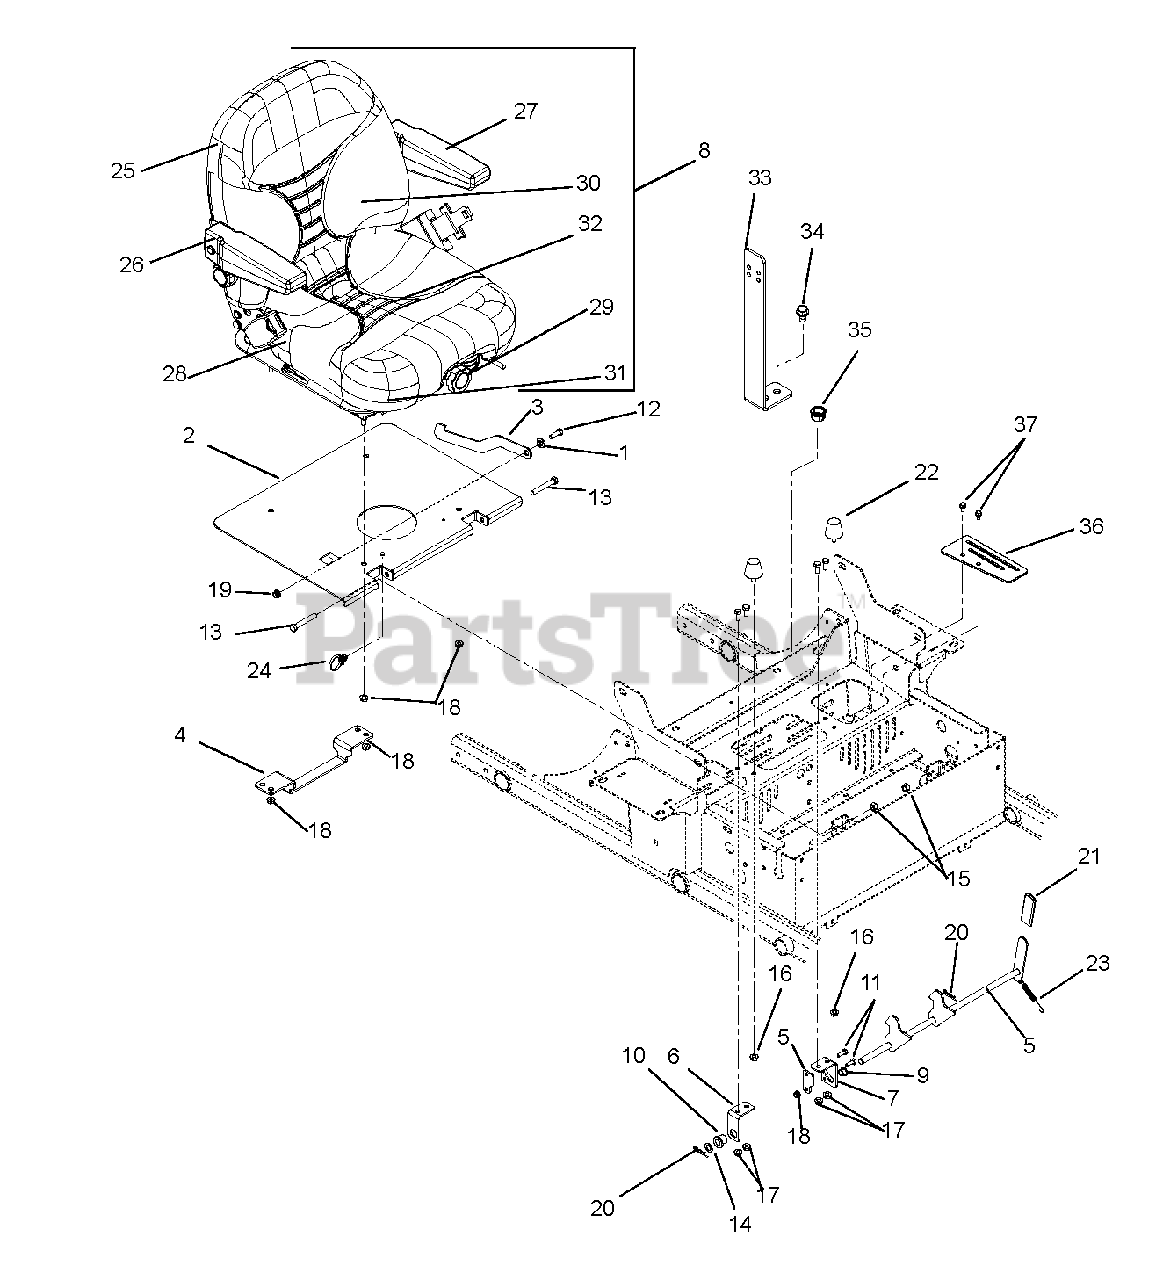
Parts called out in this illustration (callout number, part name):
1	Bushing, Flange .325 x .499 x .26 x .88
2	Seat Plate Weldment - Black
3	Stop, Seat Pivot
4	Bracket, Seat Latch
5	1Weldment, Seat Latch
6	Mount, Seat Latch -RH
7	Mount, Seat Latch -LH
8	Seat, SUSP, w/Seat Belt, LT GRY
9	Bushing, Polyliner - .50 Split
10	Bushing, Flange .515 x .750 x .745 x 1.00NY
11	Bolt, Hex .25-20 x .75 GR5 YWZC
12	Bolt, Hex .31-18 x .75 GR5 YWZC
13	Bolt, Hex .38-16 x 2.50 GR5 YWZC
14	Washer, Flat Steel .52 x .827 x .062 YWZC
15	Nut, Locking Center .38-16 YWZC
16	Nut, Spin Lock-Flange .312-18 YWZC
17	Nut, Locking Top-Flange .31-18 YWZC
18	Nut, Locking Top-Flange .25-20 YWZC
19	Nut, Locking Nylon-Flange .31-18 YWZC
20	Pin, Hair-Internal .08 x .38 x 1.42 YWZC
22	Bumper, Rubber Cone, Stud Mount
23	Spring, Tension .043 x .44 x 3.31 WLD 5.8
24	Cable Tie with Tree (.25 HOLE)
25	Kit, Back Cushion, Light Gray
26	Kit, Armrest Assembly - Right Side
27	Kit, Armrest Assembly - Left Side
28	Kit, Seat Cushion, Light Gray
29	Kit, Seat Knobs
30	Kit, Seat Back
31	Kit, Seat Slides
32	Kit, Seat, Spring and Saddle
33	Mount, Switch PT200 CE
34	Screw, Tapping .31-18 x .50 Hex Washer Head Thread Rolling (lubricated or waxed)
35	Bushing, Panel Snap .687 x .875 x .56
36	Guard, Seat Plate Finger
37	Screw, Tapping .25-20 x .50 Hex Washer Head Thread Rolling
